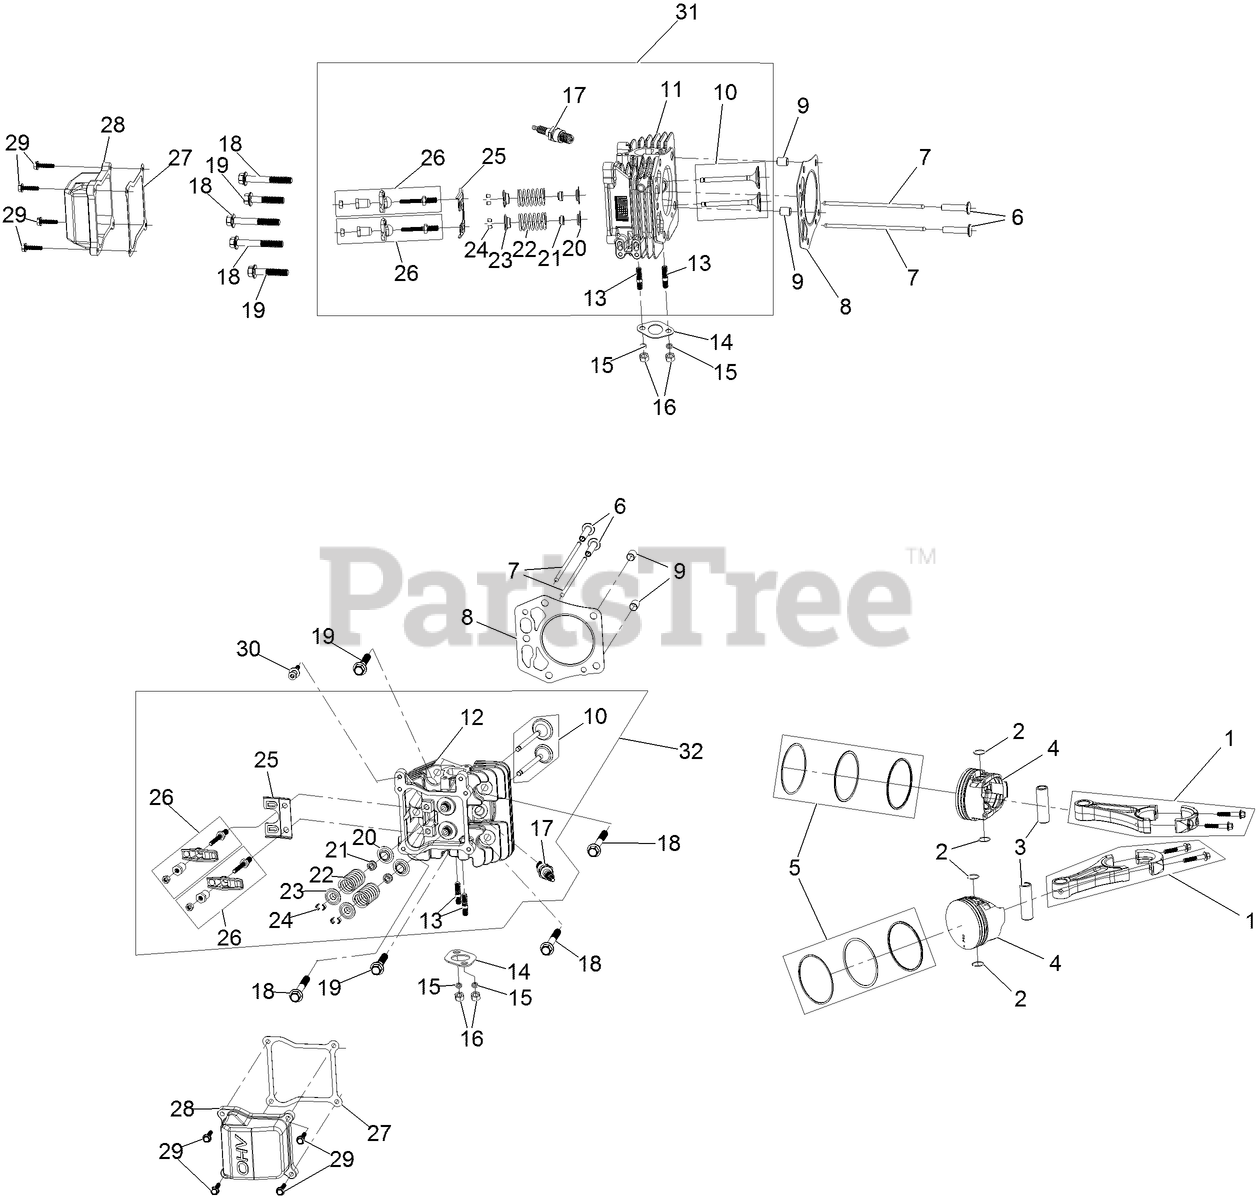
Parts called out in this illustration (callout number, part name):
1	CONNECTING ROD ASM
2	CLIP-PIN, PISTON
3	PIN-PISTON
4	PISTON
5	PISTON RING SET
6	LIFTER-VALVE
7	ROD-PUSH
8	GASKET-HEAD, CYLINDER
9	PIN-DOWEL
10	VALVE SET
11	HEAD-CYLINDER, RIGHT
12	HEAD-CYLINDER, LEFT
13	STUD-EXHAUST
14	GASKET-EXHAUST
15	WASHER-LOCK, SPLIT
16	NUT-HH
17	SPARK PLUG
18	SCREW-HWH
19	SCREW-HWH
20	SEAT-SPRING, VALVE
21	SEAL-STEM, VALVE
22	SPRING-VALVE
23	RETAINER-SPRING, VALVE
24	KEEPER-VALVE
25	PLATE-GUIDE, PUSH ROD
26	ROCKER ARM ASM
27	GASKET-VALVE COVER
28	COVER-VALVE
29	SCREW-HHF
30	SCREW-SHOULDER, HH
31	RIGHT HEAD ASM
32	LEFT HEAD ASM
